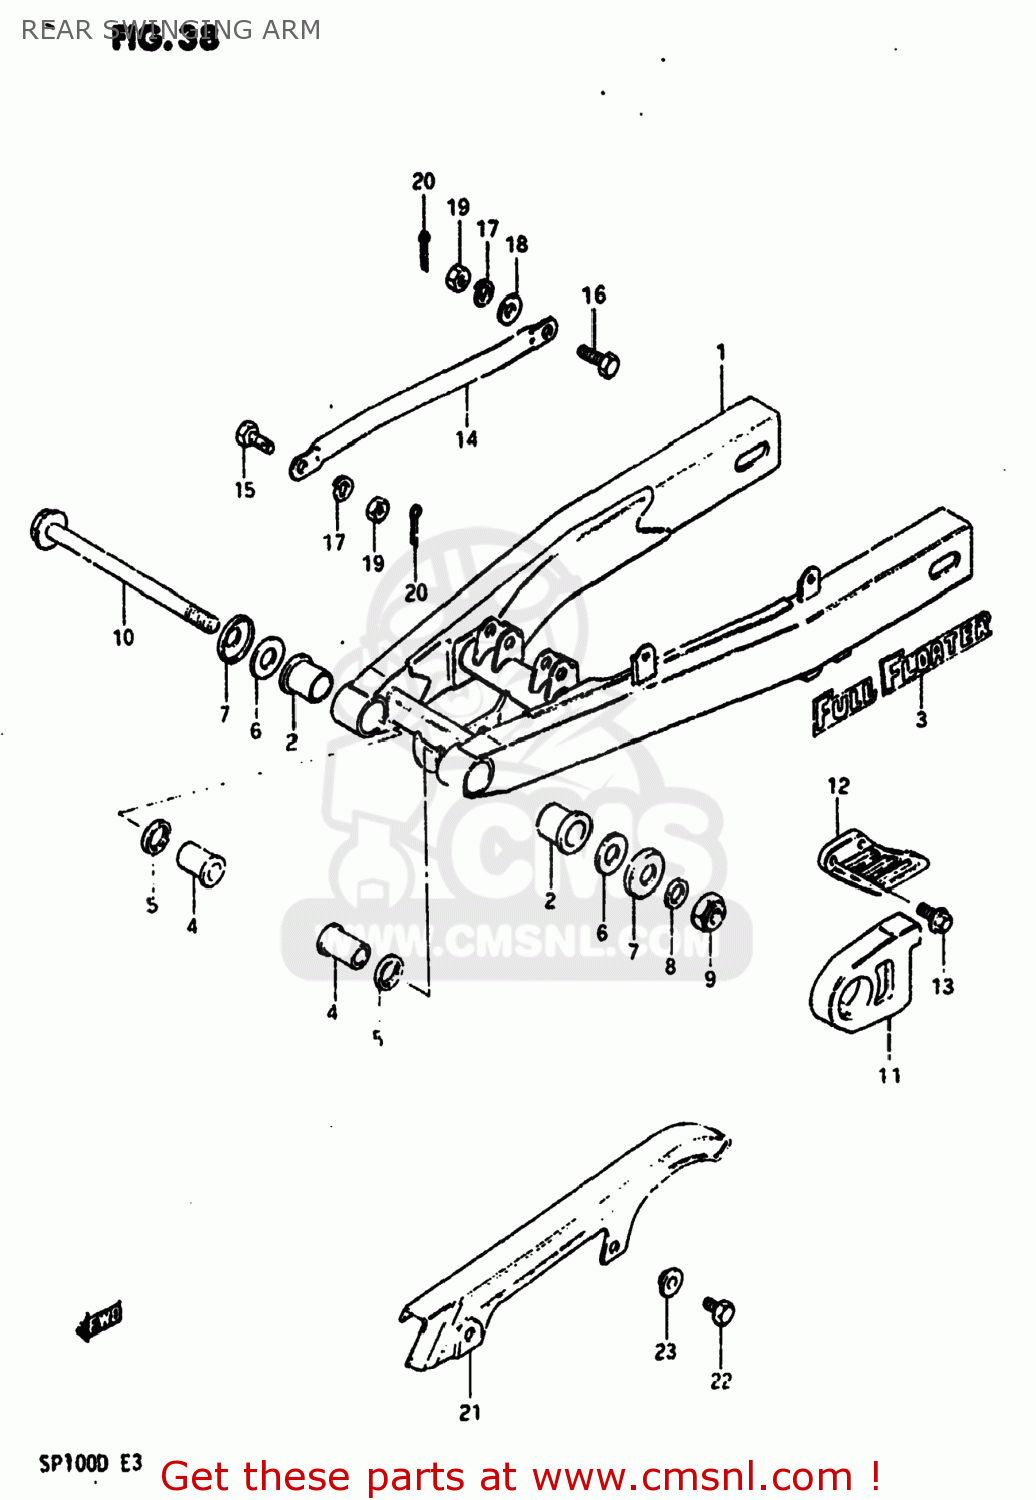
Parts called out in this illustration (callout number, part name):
1	SWING ARM ASSEMBLY,REAR
2	BUSHING,REAR SWING ARM PIVOT
3	EMBLEM,SWING ARM
4	SPACER,RR SWGARM PIVOT
5	SEAL,OIL(20X27X5)
6	WASHER
7	CVR,RR SWGARM DUST SEAL(OD:40)
8	WASHER
9	NUT 14MM
10	SHAFT,REAR SWING ARM
11	BUFFER,CHAIN TOUCH DEFLECTOR
12	GUIDE,CHAIN
13	BOLT
14	LINK,REAR TORQUE
15	BOLT(8X22)
16	BOLT(8X26.5)
17	LOCK WASHER
18	WASHER
19	NUT
20	PIN 20X20
21	CASE,CHAIN
22	BOLT
23	WASHER
